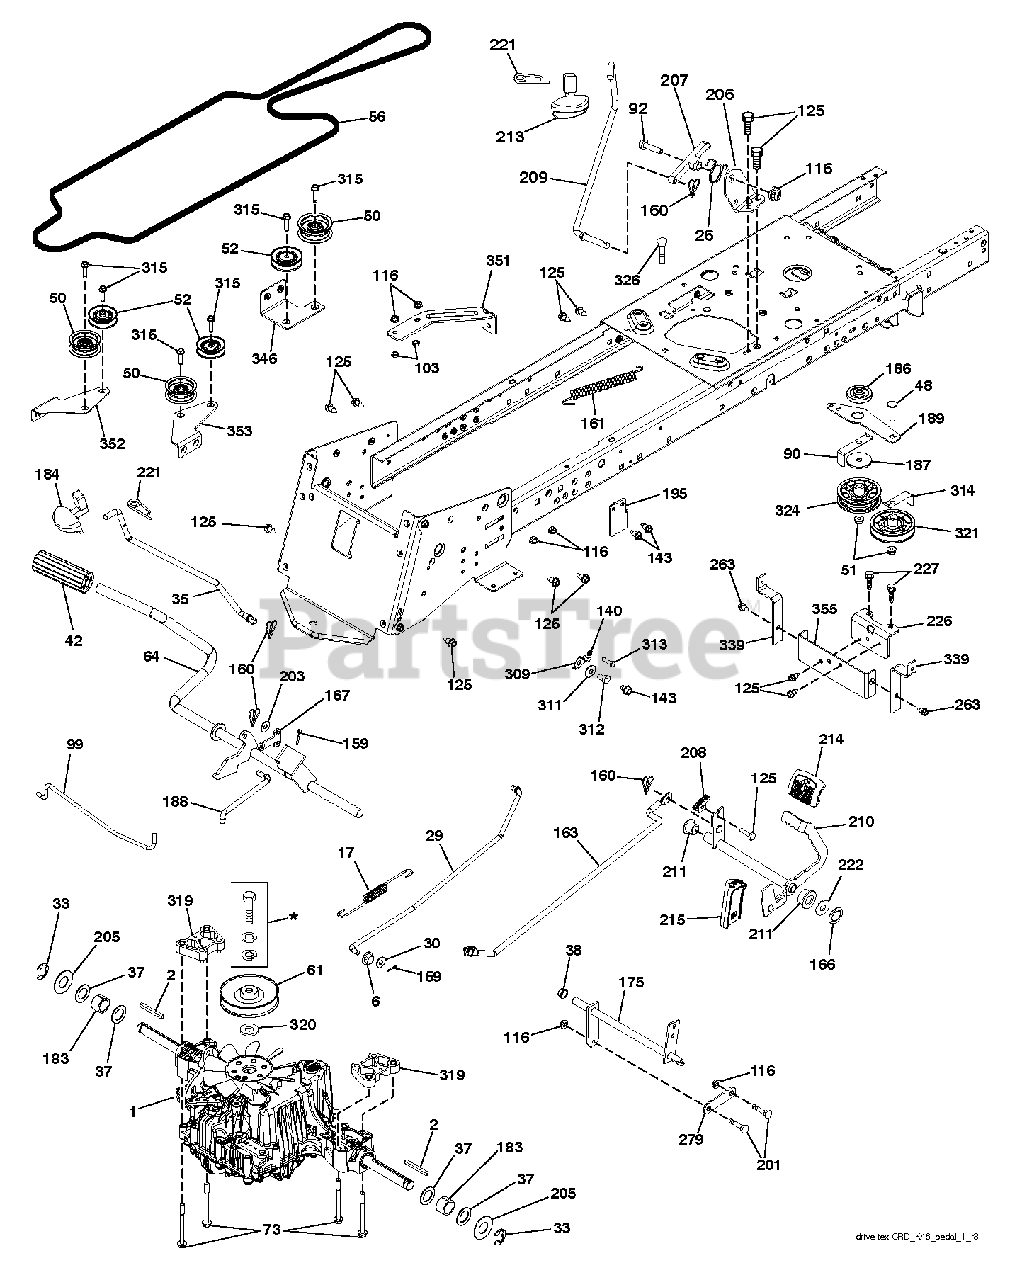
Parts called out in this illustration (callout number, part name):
2	SQUARE KEY
6	BUSHING.SNAP.NYL.BLK.
17	SPRING
26	SPRING.RETURN.CRUISE
29	ROD
30	WASHER
35	ROD.BRAKE.PARTK.HUSQ.TEX
38	NYLINER SNAP 5/8" ID
42	PEDAL COVER T
48	BOLT.3/8-16X1.50
50	IDLER.FLAT.2.25.INCH
51	NUT LOCK FLG 3/8-16 UNC
52	PULLEY.V-IDLER.
56	V-BELT 113"
61	PULLEY
64	SHAFT.ASM.PEDAL.BRK.CNTR
73	BOLT.FLANGED
90	BRACKET KEEPER BELT CLUTCHING
92	BOLT
99	ROD
103	JAM NUT TI
116	NUT LOCK HEX FLANGE 5/16-18
125	SCREW
140	LOCKWASHER
143	SCREW LT
159	COTTER PIN
160	RETAINER CLIP
161	SPRING, RETURN LT
163	ROD
166	NUT.PUSH.625
167	LATCH.BRAKE.SPRING
175	SHAFT SHAFT CROSS SHIFT REAR F
183	SPACER AXLE
184	RB HANDLE.PARKG.BRK.HUS/PRED
186	SPACER.RETAINER
187	WASHER 12/32X2X10GA
188	RP LINK.CLUTCH.GROUND.DRIVE
189	BELLCRANK BELLCRANK GROUNDDRI
201	BOLT SHOULDER 5/16-18 UNC
203	WASHER
206	BRKT.MOUNT.LATCH.CRUIS
207	LATCH.CONTROL.CRUISE
208	GEAR.SECTOR.CONTROL.CR
209	ROD.CONTROL.CRUISE.GT.
210	ROCKER.ASM.PEDAL.CONTR
211	BEARING.NYLON
213	KNOB.CONTROL.CRUSIE.HU
214	PEDAL.FORWARD.PAD.TEX
215	PEDAL RUBBER REVERSE
221	RETAINER.SPRING.CLIP.H
222	WASHER 21/32 X 1-1/4 X 10 GA.
226	BRACKET.MOUNT.TORQUE.K46.TLT
227	SCREW
263	SCREW, 3/8-16X3/4
279	LINK
309	PLATE.FASTENING.CROSS.SHAFT
311	WASHER NYL
312	HUB.TAPERED.ROUND.CRD
313	BOLT
314	RETAIN BELT
315	BOLT.5/16-18X1.25
319	SPACER SPACER TRANSAXLE TEX C
320	WASHER.SPACER.MANDREL
321	IDLER PULLEY
326	BOLT CARRIAGE
339	STRAP STRAP TORQUE K46 CRD TE
351	BRACKET BRACKET DECK SWAY
352	BRACKET BRACKET.IDLER
353	BRACKET
355	STRAP STRAP TORQUE K46 CRD TEX
